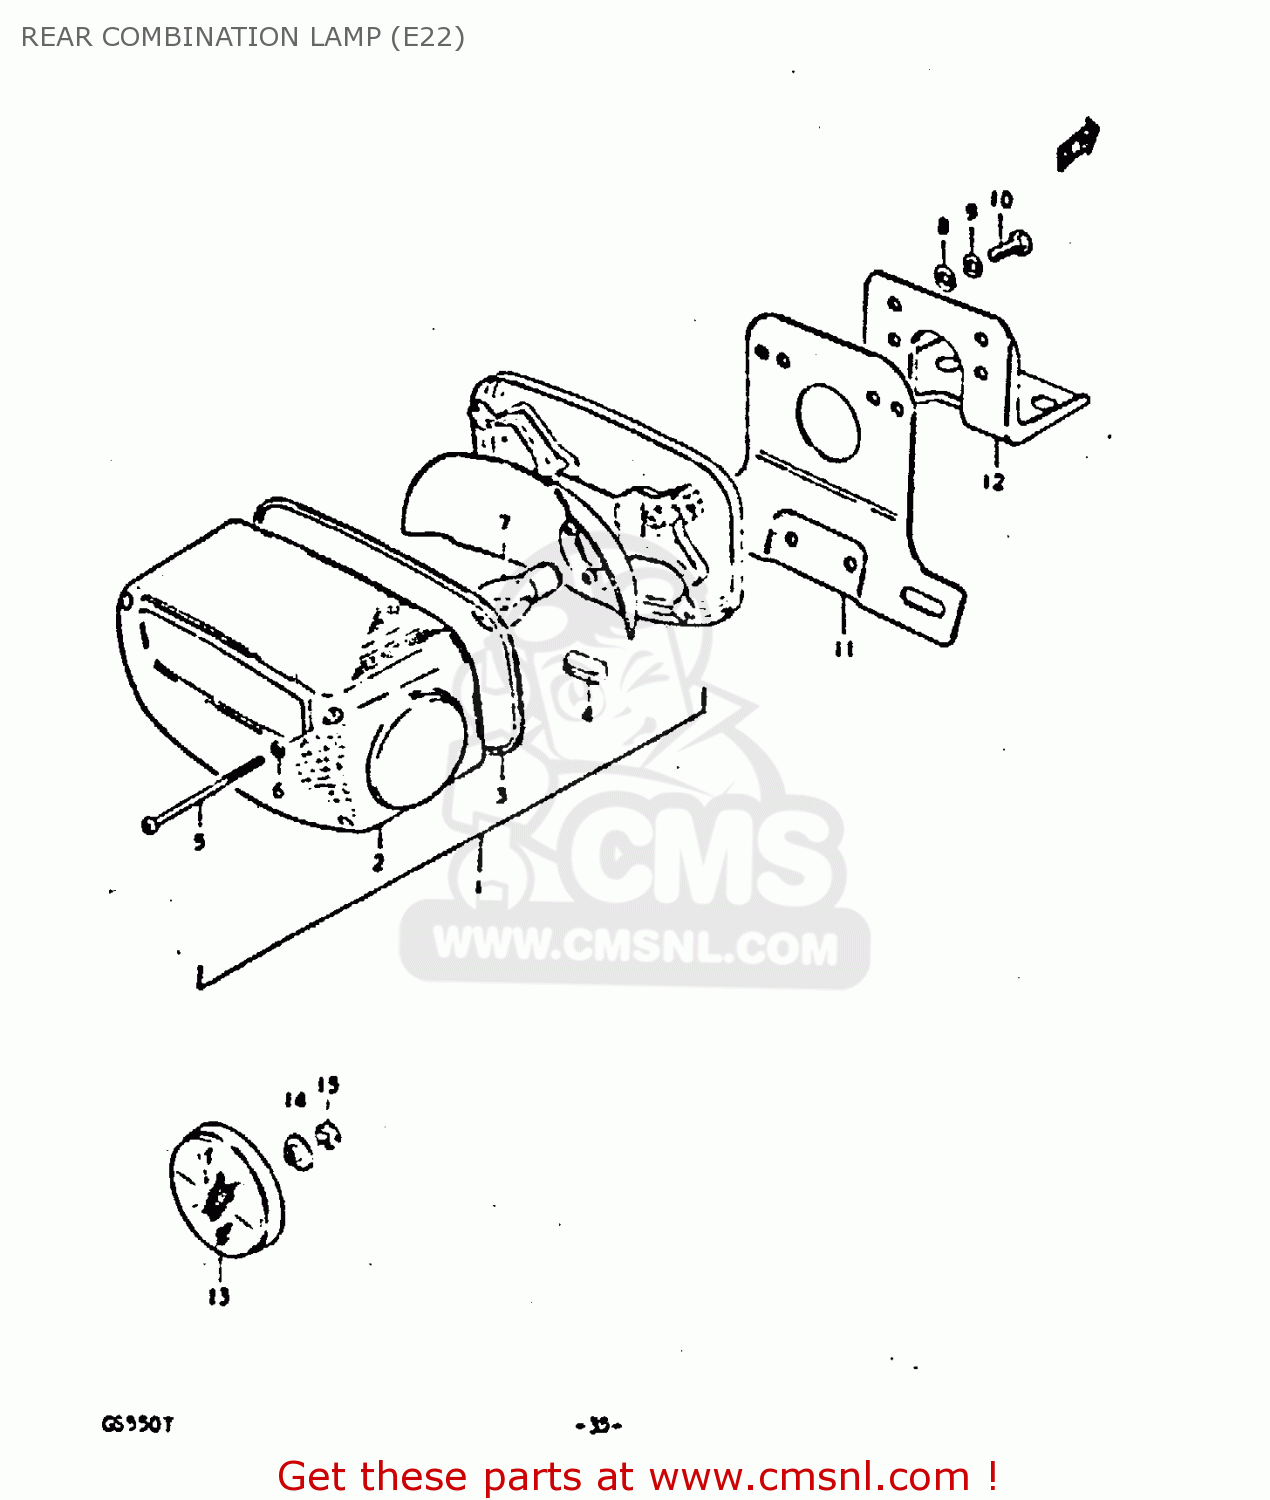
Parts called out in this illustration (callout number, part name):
1	LAMP ASSY, REAR COMBINATION
2	LENS,RR COMBIN
3	GASKET (NAS)
4	GROMMET
5	SCREW (4X55)
6	GASKET (NAS)
7	BULB(12V21/5W)
8	WASHER
9	LOCK WASHER
10	BOLT
11	PLATE, LICENCE
12	BRACKET,LICENSE PLATE
13	REFLECTOR,REFLEX
14	SPACER
15	NUT
